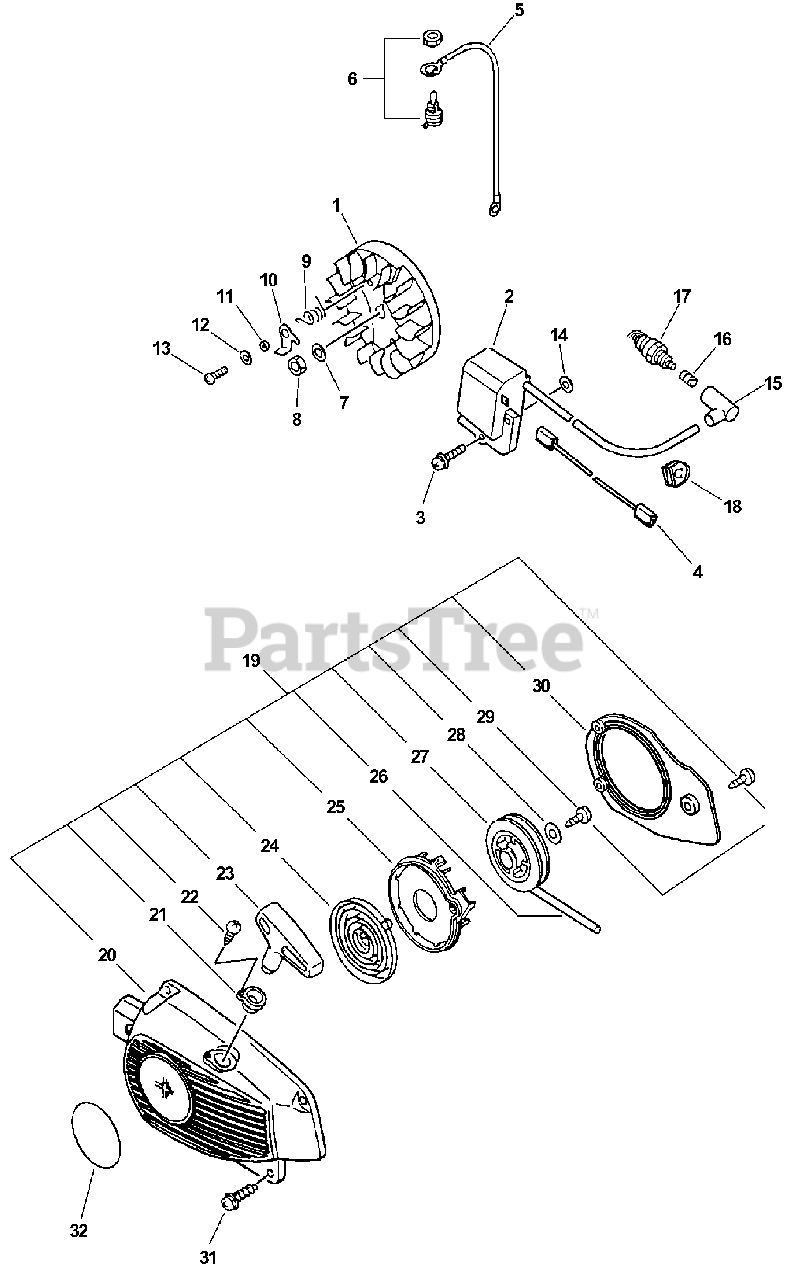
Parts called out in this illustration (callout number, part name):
1	FLYWHEEL
2	COIL, IGNITION
3	SCREW 5×20
3	SCREW 5×22
4	LEAD - IGNITION L= 95
5	LEAD - GROUND L= 100
6	SWITCH, ON-OFF
7	WASHER 8.5×16×1.2
9	SPRING, TORSION
10	PAWL, STARTER
11	SPACER 5.2×8×2.1
12	WASHER 5.5×12×0.8
13	SCREW 5×12
14	WASHER 5.2×12×3
15	CAP, SPARK PLUG
16	TERMINAL, SPARK PLUG
17	SPARK PLUG - BPM7A
17	SPARK PLUG - BPMR7A
19	STARTER ASSY
20	CASE, STARTER
21	GUIDE, ROPE
22	SCREW 3×14
23	GRIP, STARTER
24	SPRING, RECOIL
25	PLATE, STARTER
26	ROPE, STARTER 3.0×850
27	REEL, ROPE
28	WASHER 4.1×15.5×1T
29	SCREW 4×14
31	SCREW 4×16
32	LABEL, ECHO
